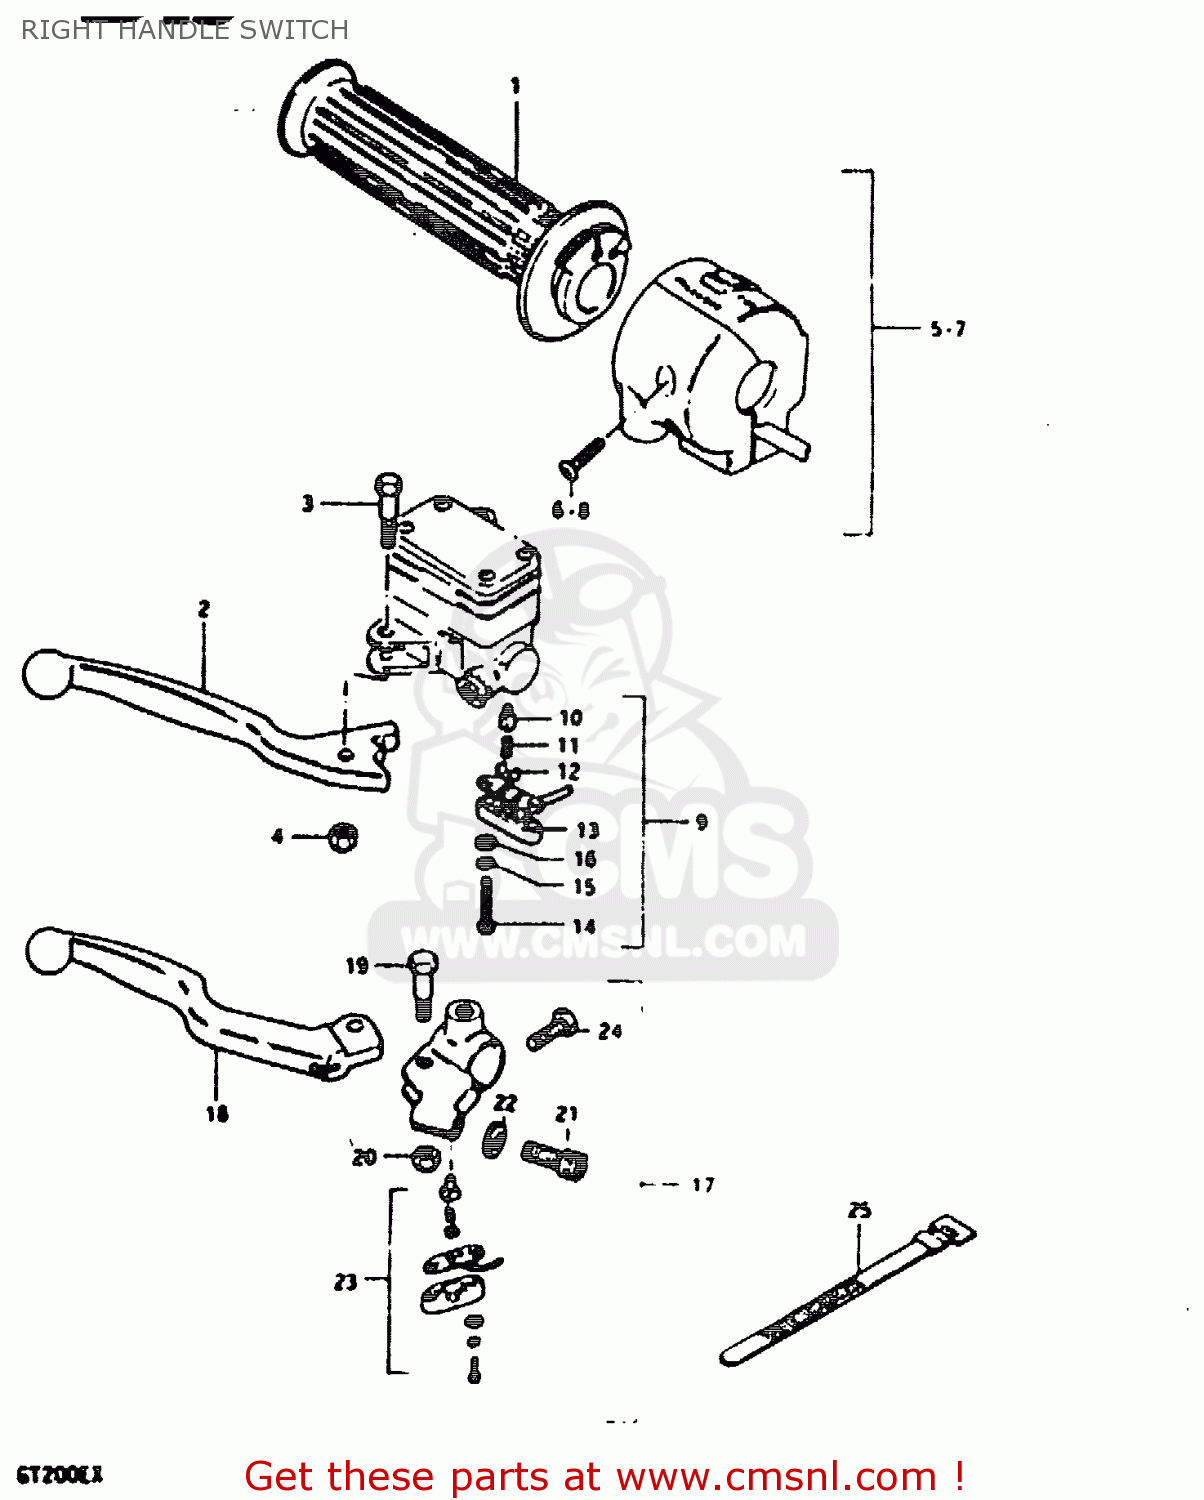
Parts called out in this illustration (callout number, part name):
1	GRIP,THROTTLE
2	LEVER,BRAKE
3	BOLT
4	NUT 6MM
5	SWITCH ASSY, HANDLE RH
6	SCREW
17	LEVER ASSY, BRAKE
18	LEVER,BRAKE
19	BOLT,LEVER
20	NUT 6MM
21	ADJUSTER,CABLE
22	NUT,CABLE ADJUSTER
23	SWITCH ASSY, STOP
24	BOLT,CLUTCH LEVER HOLDER
25	CLAMP(L:120)
